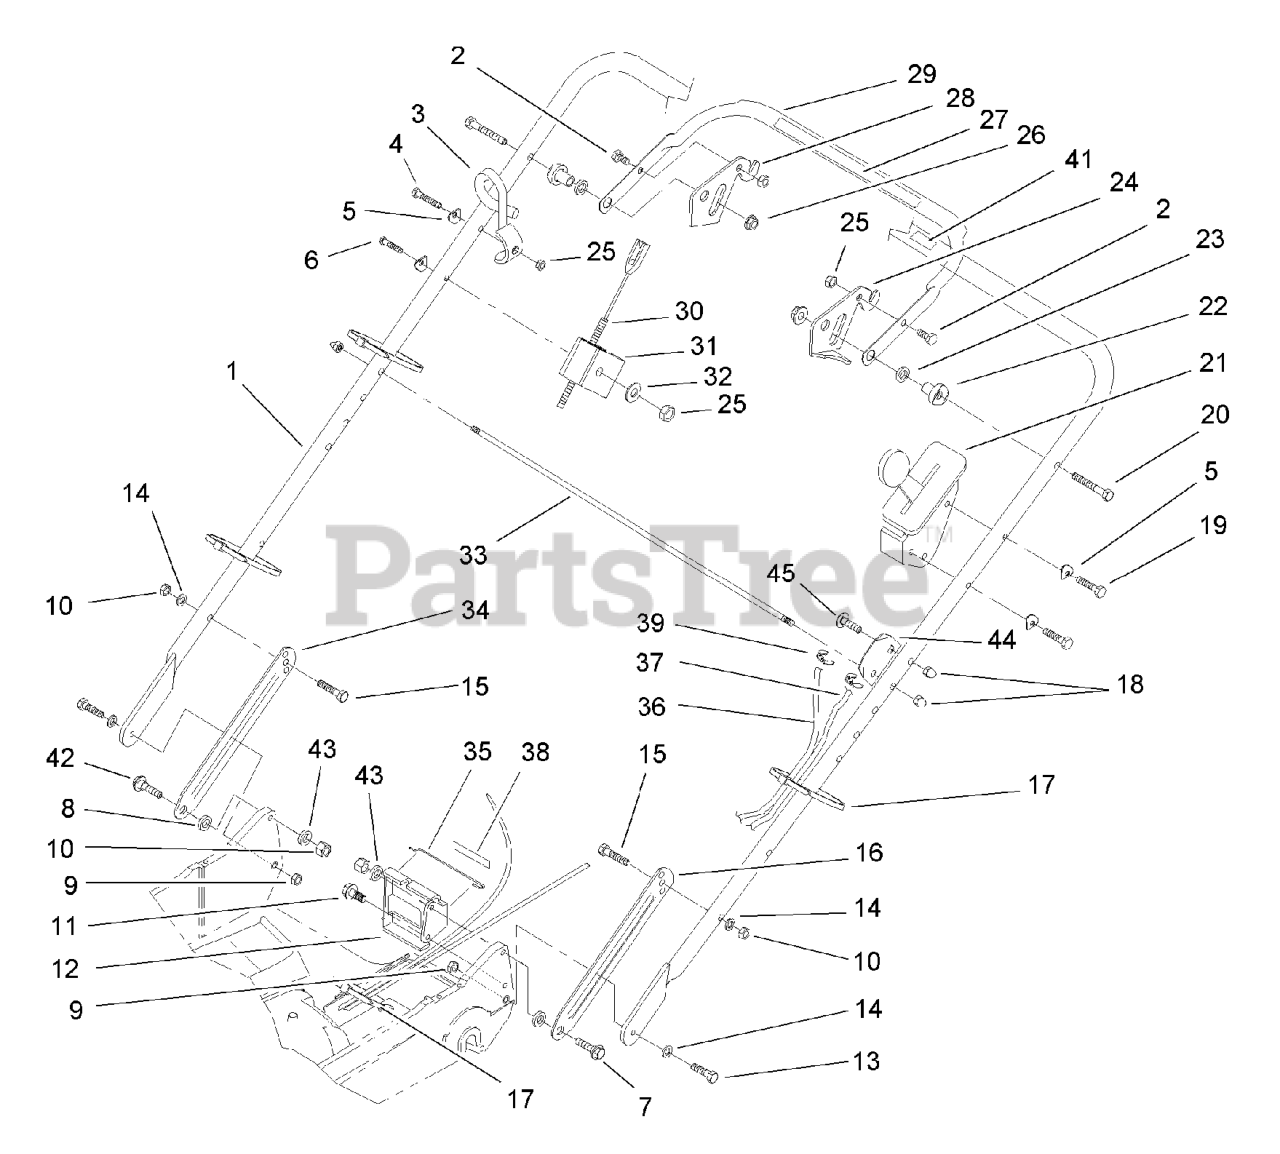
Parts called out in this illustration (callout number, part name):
2	SCREW-HH
3	GUIDE-ROPE
4	SCREW-HH
5	WASHER
6	SCREW-HH
7	SCREW-SHOULDER
8	SPACER
9	NUT-LOCK, NI
10	NUT-LOCK, NI
11	Screw-HWH 5/16-18 X 3/4 Tf
12	BRACKET-ADJUSTMENT, TRACT
13	SCREW-HH
14	WASHER-BELLEVILLE
15	SCREW-HH
17	TIE-CABLE
18	NUT-CAP
19	SCREW-HH
20	SCREW-HH
22	SPACER-SUPPORT
23	SPACER-NYLON
24	LEVER-CONTROL
25	NUT-LOCK, NI
26	NUT-LOCK, NI
28	LEVER-CONTROL
29	BAR-CONTROL
30	CABLE-BRAKE
31	SUPPORT-CABLE
32	WASHER-FLAT
33	ROD-SUPPORT, BAG
35	RETAINER-CABLE
36	CABLE-TRACTION
37	THROTTLE CABLE ASM
38	DECAL-POSITION, GEAR
41	DECAL-PROTECTION, HEARING
42	SCREW-SHOULDER
43	WASHER-PLAIN
45	SCREW-CARR
